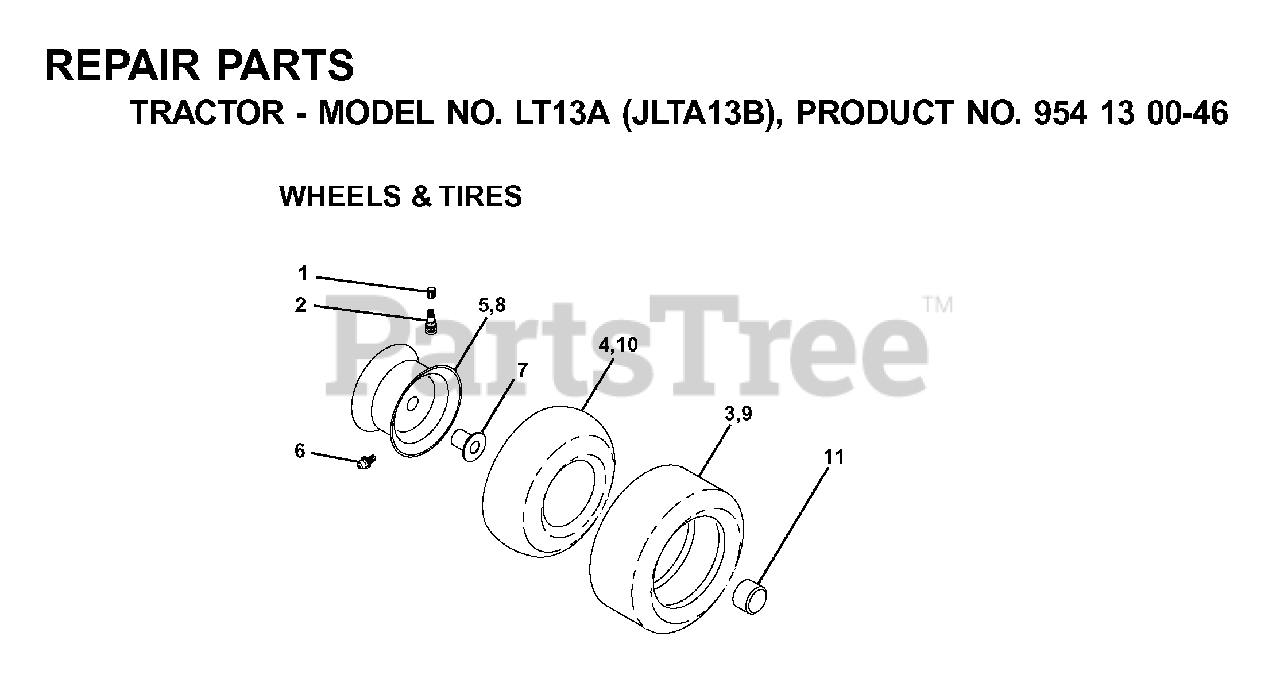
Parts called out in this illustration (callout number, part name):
1	VALVE CAP
2	VALVE STEM LT
3	TIRE HEAVY DUTY
4	TUBE.5.3/4.5/6
5	RIM ASM 6" FRONT SILVER
6	FITTING LT
7	BEARING T
8	RIM ASM 8" REAR SILVER
9	TIRE
10	TUBE
11	CAP, AXLE BLK
